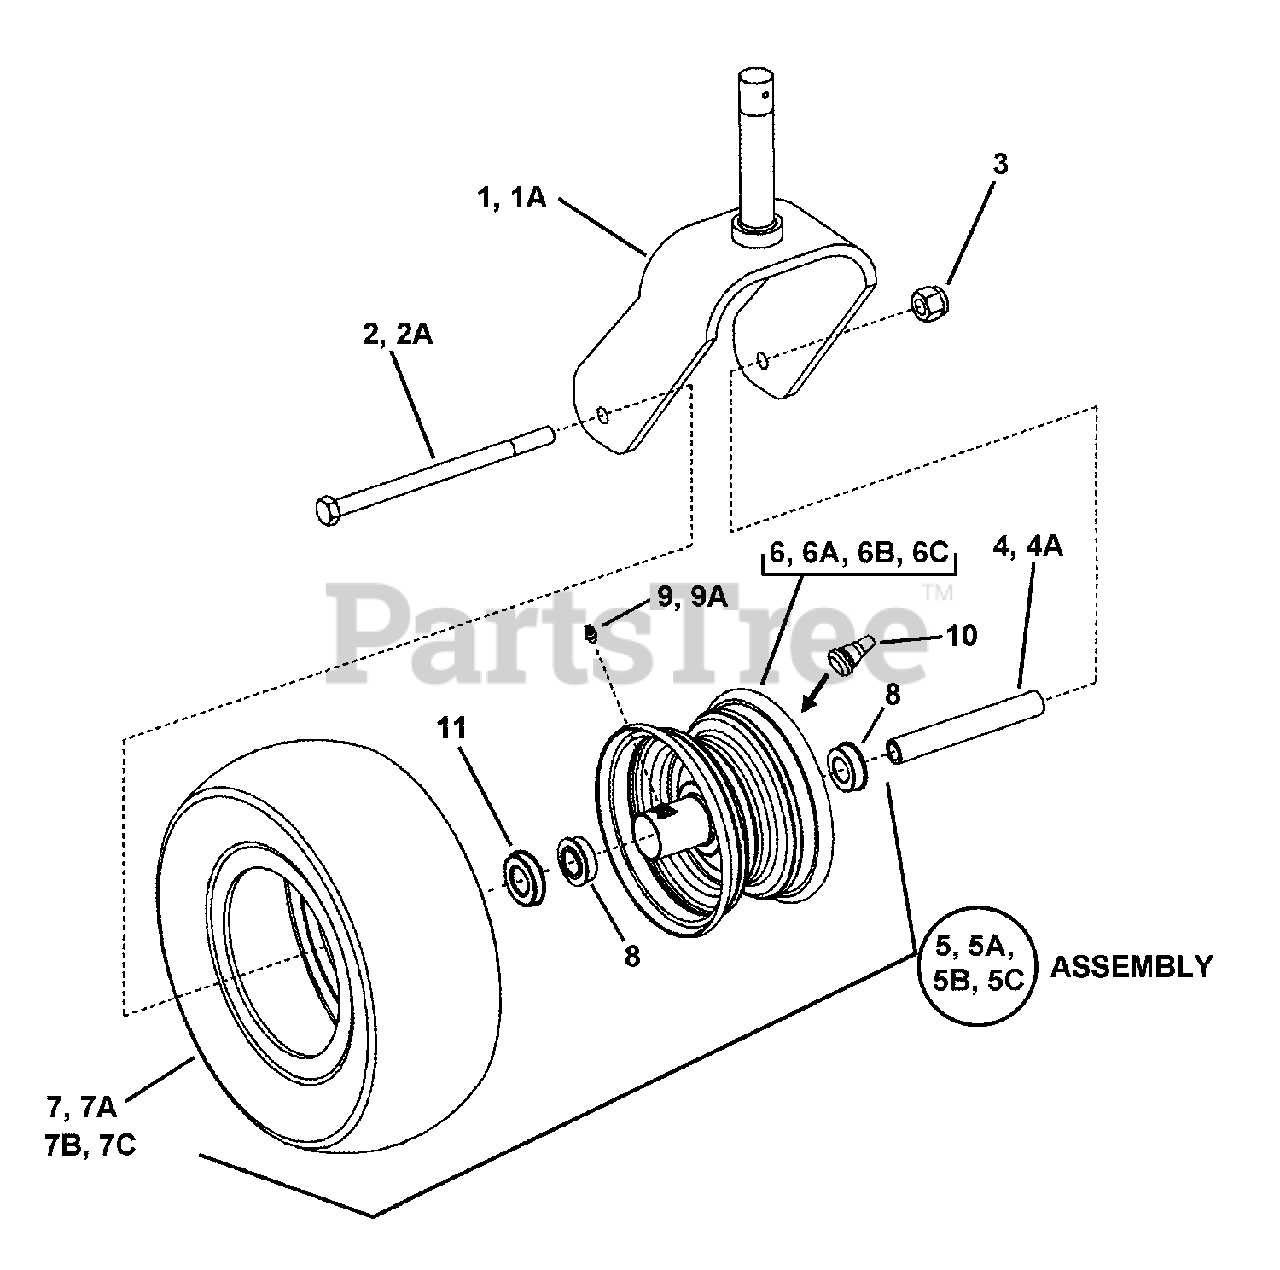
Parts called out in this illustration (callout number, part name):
1	WELDMENT, Caster Yoke
1A	WELDMENT, Caster Yoke, 7-1/4" Wide
2	BOLT, HEX, 1/2-13 X 7, GD 8, YZ
2A	SCREW, 1/2-13 x 9-1/2" Hex Head Cap, GR 5
3	NUT,1/2-13 Nyloc
4	SPACER, Bearing, 5.29" Long
4A	SPACER, Bearing, 7.29" Long
5	ASSY, Tire & Wheel (Incl. items 6 thru 11)
5A	ASSY, Tire & Wheel (Incl. items 6A, 7A, 8, 9A, 10 & 11)
5B	ASSY, Tire & Wheel (Incl. items 6B, 7B, 8, 9, 10 & 11)
5C	ASSY, Tire & Wheel (Incl. items 6C, 7C, 8, 9, 10 & 11)
6	WELDMENT, Wheel Hub & Rim (Grey)
6A	WELDMENT, Wheel Hub & Rim (Grey)
6B	WELDMENT, Wheel Hub & Rim (Grey)
6C	WELDMENT, Wheel Hub & Rim (Grey)
7	TIRE, 13 x 5.06 4 Ply Slick
7A	TIRE, 13 x 6.5-6 4 Ply Slick
7B	TIRE, 13 x 5.00-6 4 Ply Smooth TL
7C	TIRE, 13 x 6.5-6 4 Ply Smooth TL
8	BEARING, .750 Heim
9	FITTING, Lube
9A	FITTING, Lube, 1/4-28 Thread
10	VALVE STEM, Air
11	SPACER
